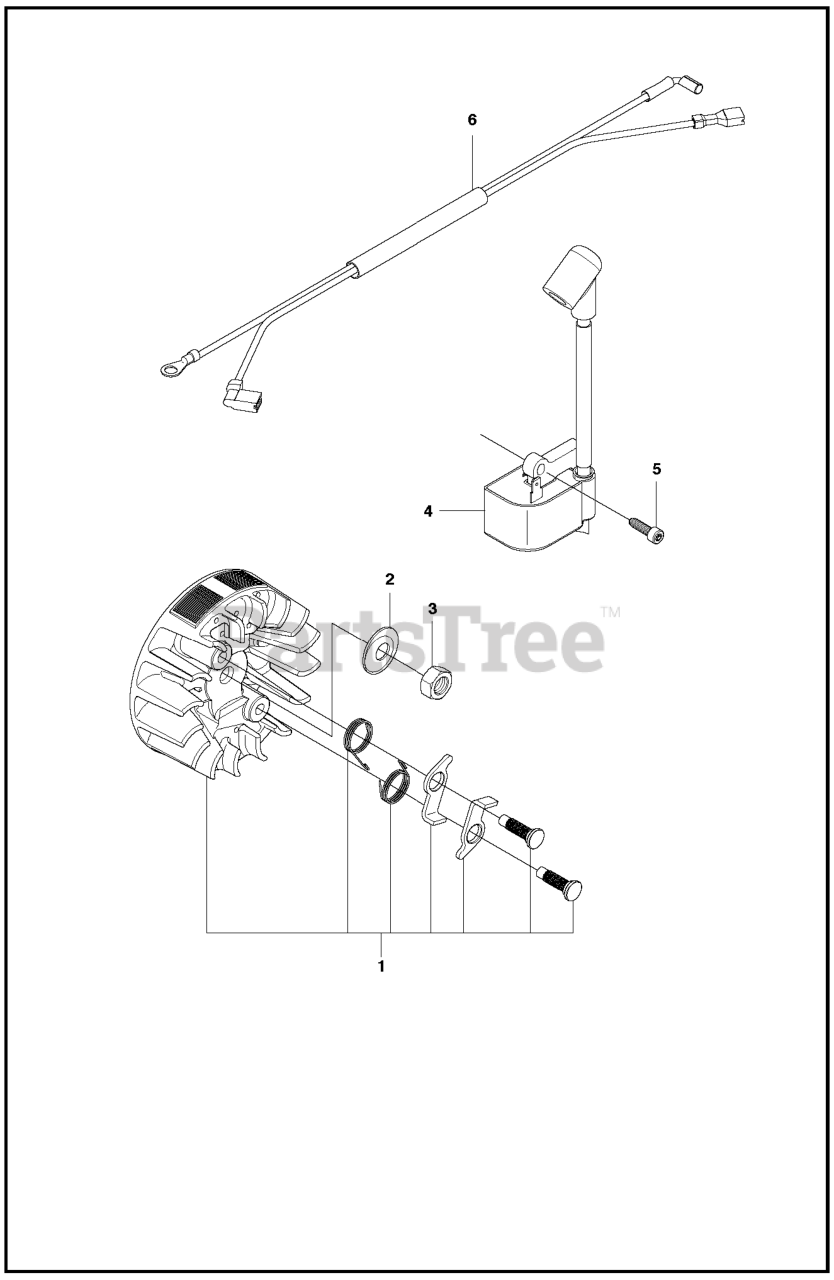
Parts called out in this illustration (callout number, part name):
1	ASSY FLYWHEEL FENGLONG P021
2	WASHER-FLYWHEEL
3	NUT-FLYWHEEL
4	MODULE
5	SCREW
6	WIRE HARNESS ASSY
